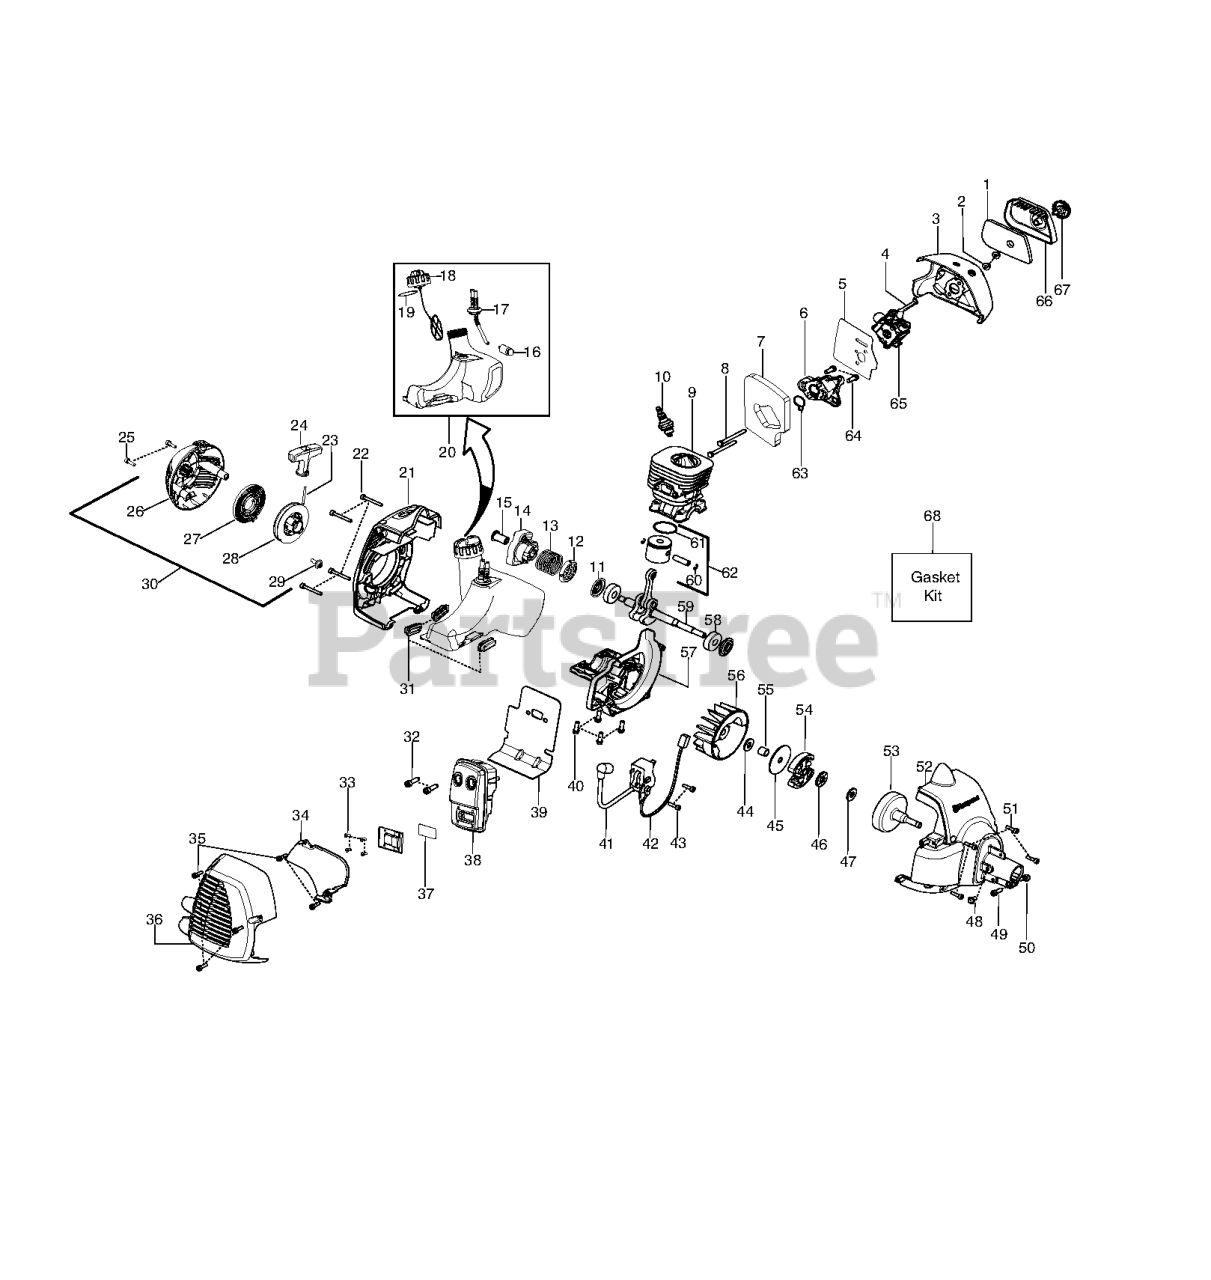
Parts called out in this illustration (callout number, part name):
1	FILTER AIRBOX
3	RP_AIR BOX
4	CHOKE LEVER
5	KIT GASKET CARB
6	CARB ADAPTOR
7	KIT GASKET 28CC
8	BOLT CARB ADAPTOR
9	CYLINDER
10	Plug - Spark (RCJ-8Y)
11	KIT SEAL CRANKSHAFT
12	WASHER STARTER
13	SPRING STARTER CUP
14	ASSY STARTER CUP
15	COUPLING STARTER
16	FUEL PICK-UP ASSY
17	KIT FUEL LINE
18	ASSY-CAP W/RETAINER
19	KIT GASKET 28CC
20	ASSY FUEL TANK HVA
21	REAR SHROUD
24	STARTER HANDLE GRAY
25	SCREW M5-0.8X30MM
26	STARTER HOUSING
27	%KIT STARTER SPRING
28	KIT STARTER PULLEY
30	ASSY-STARTER HSG.
31	ISOLATOR FUEL TANK
32	BOLT MUFFLER
33	SCREW-10-16 X 1/2 HI-LO
34	SHIELD HEAT
35	SCREW M4 X 1.75 PT 16MM
36	GUARD-MUFFLER
37	KIT SPARK ARRESTOR SCREEN
38	ASSY-MUFFLER
39	KIT GASKET 28CC
40	SCREW-M5-0.8 X 25MM(TAP)
41	IGNITION MODULE MBU-7
42	ASSY MODULE LEAD WIRE
43	SCREW M4 X .70 TT 16MM
44	WASHER CLUTCH
45	WASHER-CLUTCH
46	BEARING THRUST
47	WASHER THRUST
50	LOCKNUT-HEX 10-24
51	SCREW M4 X .70 TT 16MM
52	FAN HSG ASSY
53	ASSY-CLUTCH DRUM
54	%KIT CLUTCH ASSY
55	SPACER FLYWHEEL
57	CRANKCASE CASTING
58	BEARING RADIAL BALL (6201)
59	KIT CRANKSHAFT ASSY
60	WRIST PIN RET.
61	RING PISTON
62	KIT PISTON 28CC TRIMMER
63	KIT GASKET 28CC
64	SCREW-M5-0.8 X 25MM(TAP)
66	COVER-AIR BOX
67	KNOB ASSY AIRBOX COVER
68	KIT GASKET 28CC
